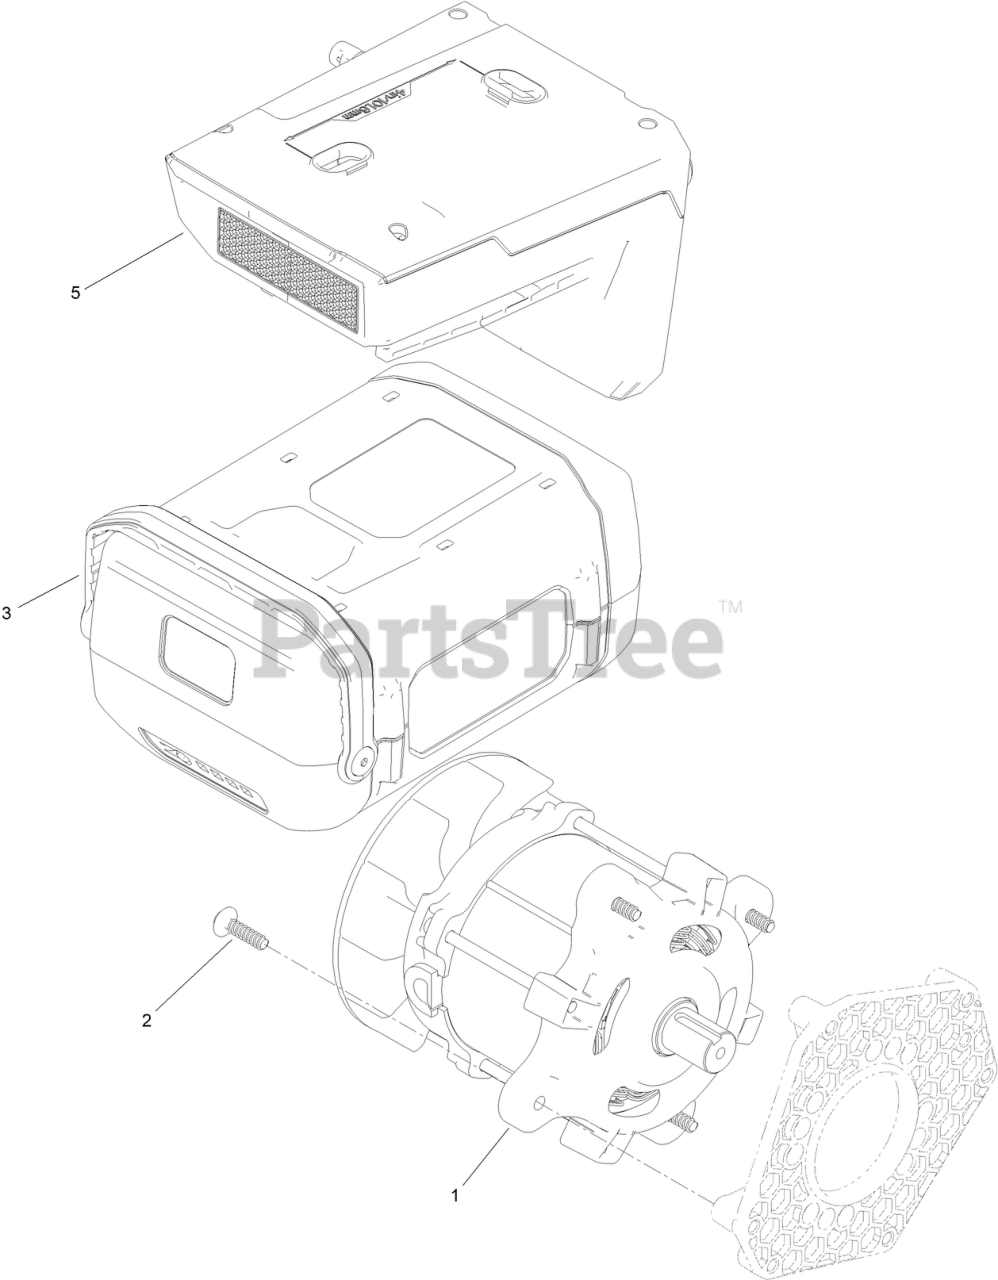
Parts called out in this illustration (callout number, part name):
1	MOTOR- E21SP
3	BATTERY-LI-ION, 60V 10 AH, DOM
5	CHARGER-60V
